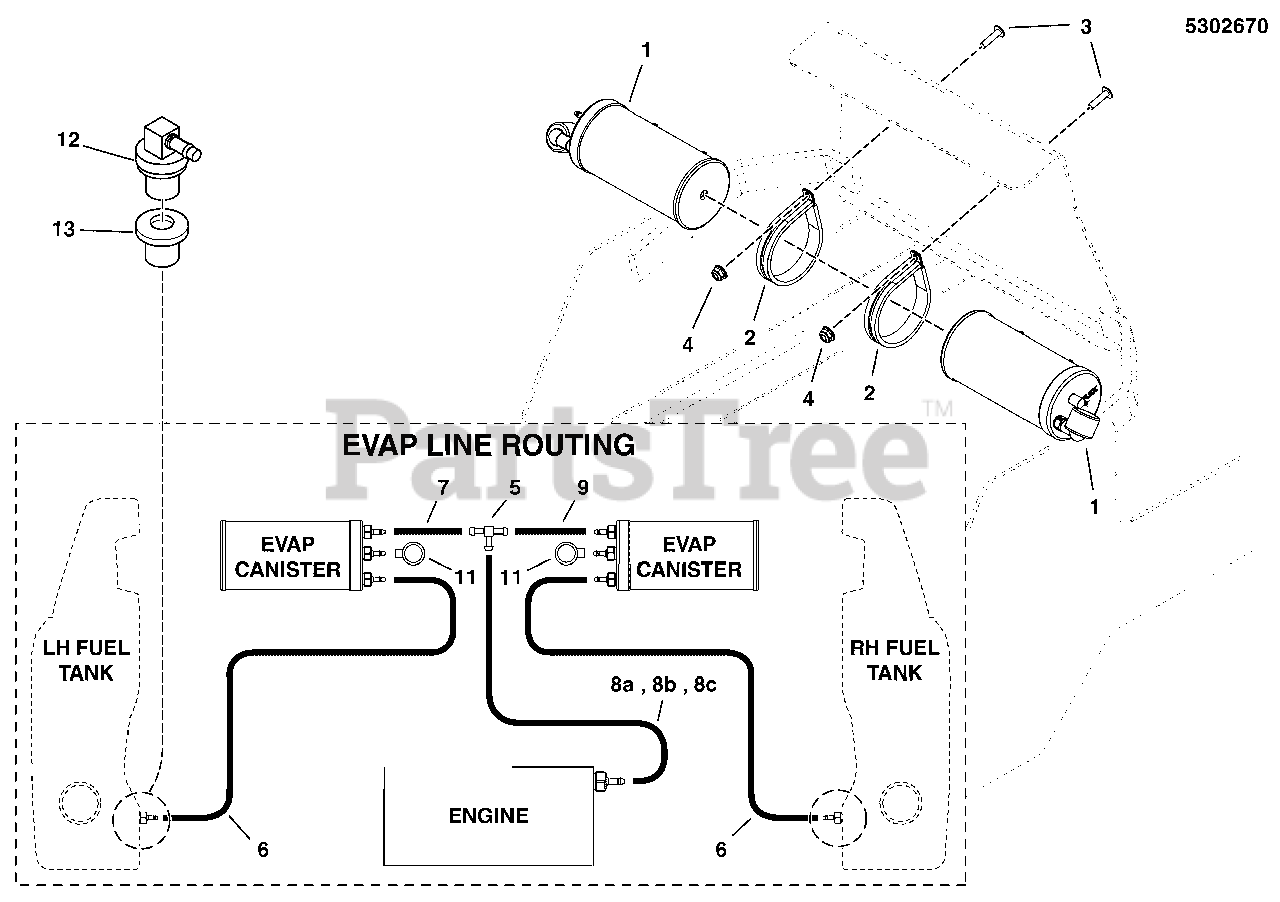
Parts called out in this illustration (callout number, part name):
1	CNSTR, CARB, 6 GAL
2	CLAMP, 3" ID, CUSHIONED, STAINLESS
3	BOLT, 1/4-20 X 3/4, ALLEN BUTTON HD, YZ
4	NUT, 1/4-20 HEX NYLOCK FLANGE
5	FITTING, 3/16" TEE, BARB TYPE, HDPE
6	HOSE, VAPOR, 5MM ID, 10.50 LG
7	HOSE, VAPOR, 5MM ID, 11.00 LG
9	HOSE, VAPOR, 5MM ID, 21.50 LG
10	DECAL, EPA CERT, ZTRS
11	DUST FILTER, CANISTER
12	REMOTE VENT ASSY, NO VALVE
13	GROMMET
